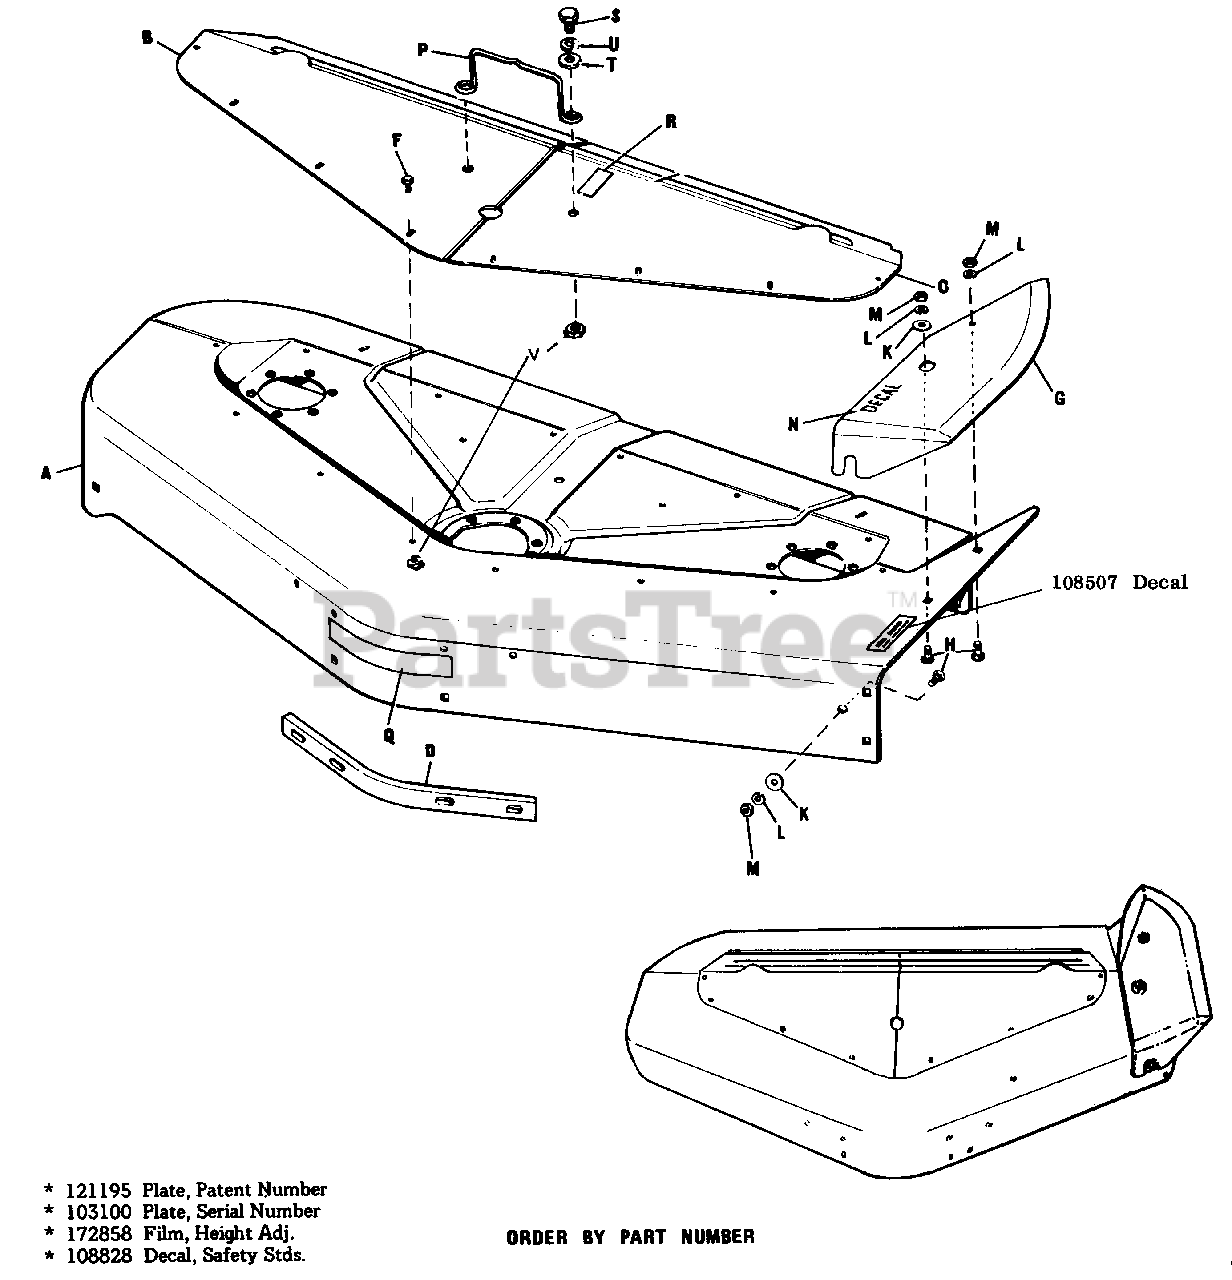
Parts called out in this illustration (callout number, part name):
A	Mower Housing
B	R.H. Cover
C	L.H. Cover
D	Reinforcing Bar
F	Self Tapping Screw, 1/4"-20 x 3/8"
G	Deflector
H	Carriage Bolt, 3/8"-16 x 3/4"
K	Special Washer
L	Lock Washer, 3/8"
M	Hex. Nut, 3/8"-16
P	Guide Belt
Q	Film Simplicity
R	Film-Belt Instructions
S	Hex. Cap Screw, 5/16"-18 x 3/4"
T	Plain Washer, 5/16"
U	Lock Washer, 5/16"
V	Nut Retainer, 5/16"
